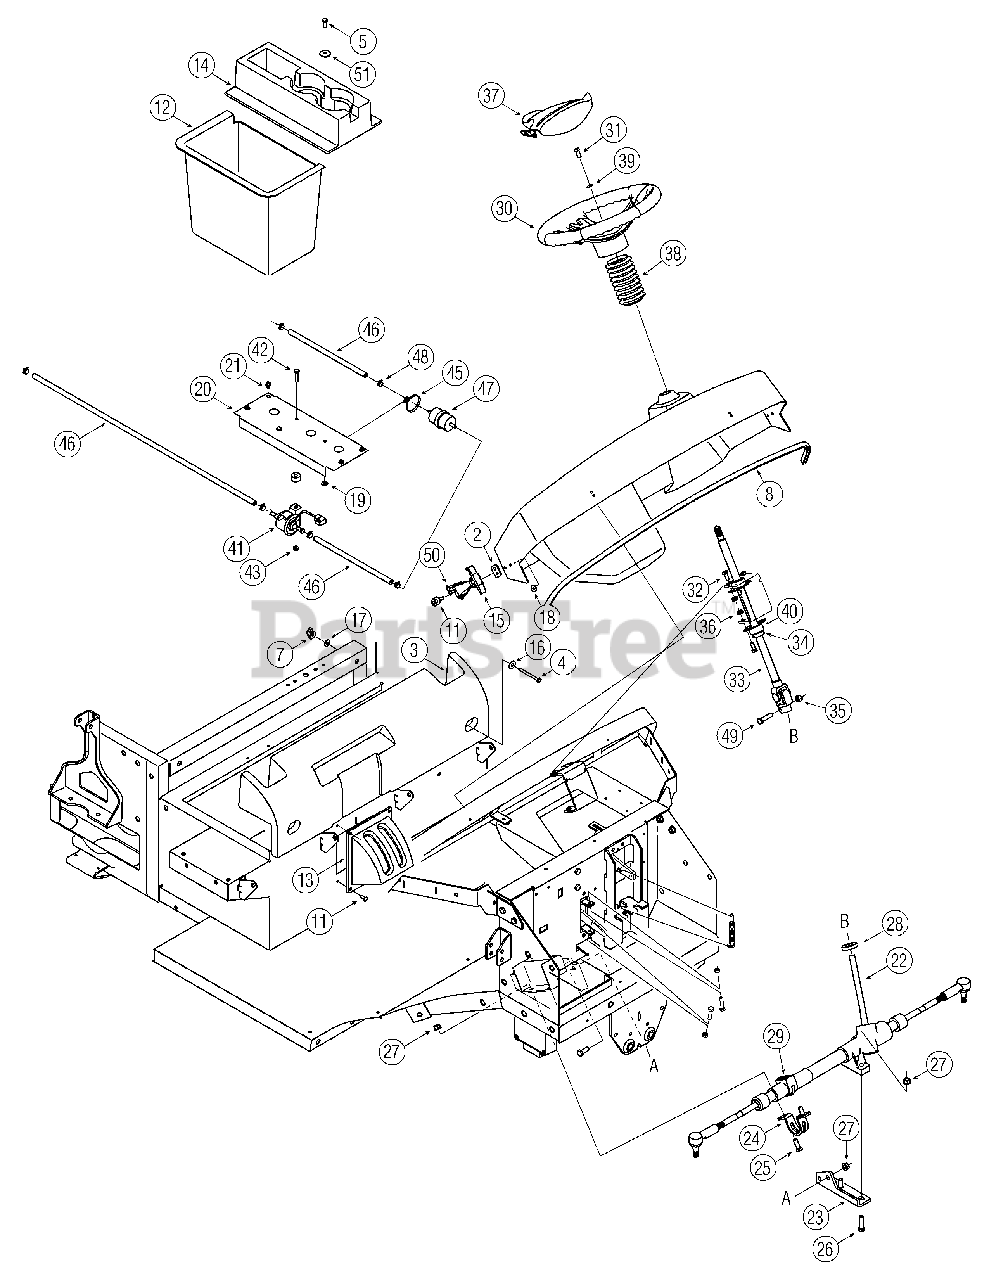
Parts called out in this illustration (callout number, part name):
1	Dash Assembly
2	Hood Mounting Plate
3	Panel, Airbox Cover
4	Hex Screw, 1/4-20 x 2.75
5	Hex Screw, 5/16-18 x0.5, Gr5
7	Wing Nut, 1/4-20
8	Trim, Bulb Seal, 1/4
9	Foot Pad, Abrasive
10	Rivet, Pop,.187
11	Rivet, Pop,.188
12	Container, Bulkhead
13	Panel, Shift Cover
14	Console, Cup Holder
15	Handle, Latch
16	Flat Washer, 349 x.875 x.04
17	Washer, Flat,.28 x.74 x.063
18	Washer, Flat,.194 x.62 x.063
19	Washer, Flat,.25 x.630 x.0515
22	Gear Assembly, Steering
25	Hex Screw, 3/8-16, 1.00, Gr8
26	Hex Screw, 3/8-16, 1.50, Gr5
27	Nut, Flange Lock, 3/8-16
28	Grommet, Steering Shaft
29	Bushing, Rubber
30	Wheel, Steering
31	Hex Screw, 5/16-18,.75, Gr5, Patch
32	Hex Screw, 5/16-18, .75, Gr5
33	Shaft, Steering, 5/8 Spline
34	Collar, .75
35	Nut, Hex Lock Nylon, 3/8-16
36	Nut, Flange Lock, 5/16-18
37	Cover, Steering Wheel
38	Bellow, Steering, 4.75 Lg
39	Washer, Bell,.340 x.872 x.060
40	Bearing, Flange,.75 ID, Self-Aligning
41	Pump Assembly, Fuel
42	Hex Screw, 1/4-20 x 1.25
43	Flange Lock Nut, 1/4-20
44	Bushing,.96OD x.50
45	Cable Tie
46	Fuel Line Hose
47	Fuel Filter
48	Clamp, Hose
49	Hex Screw, 3/8-16 x 1.75, Gr5
50	Rivet. Pop, .450
51	Washer, Bell .39 x 1.38 x .062
